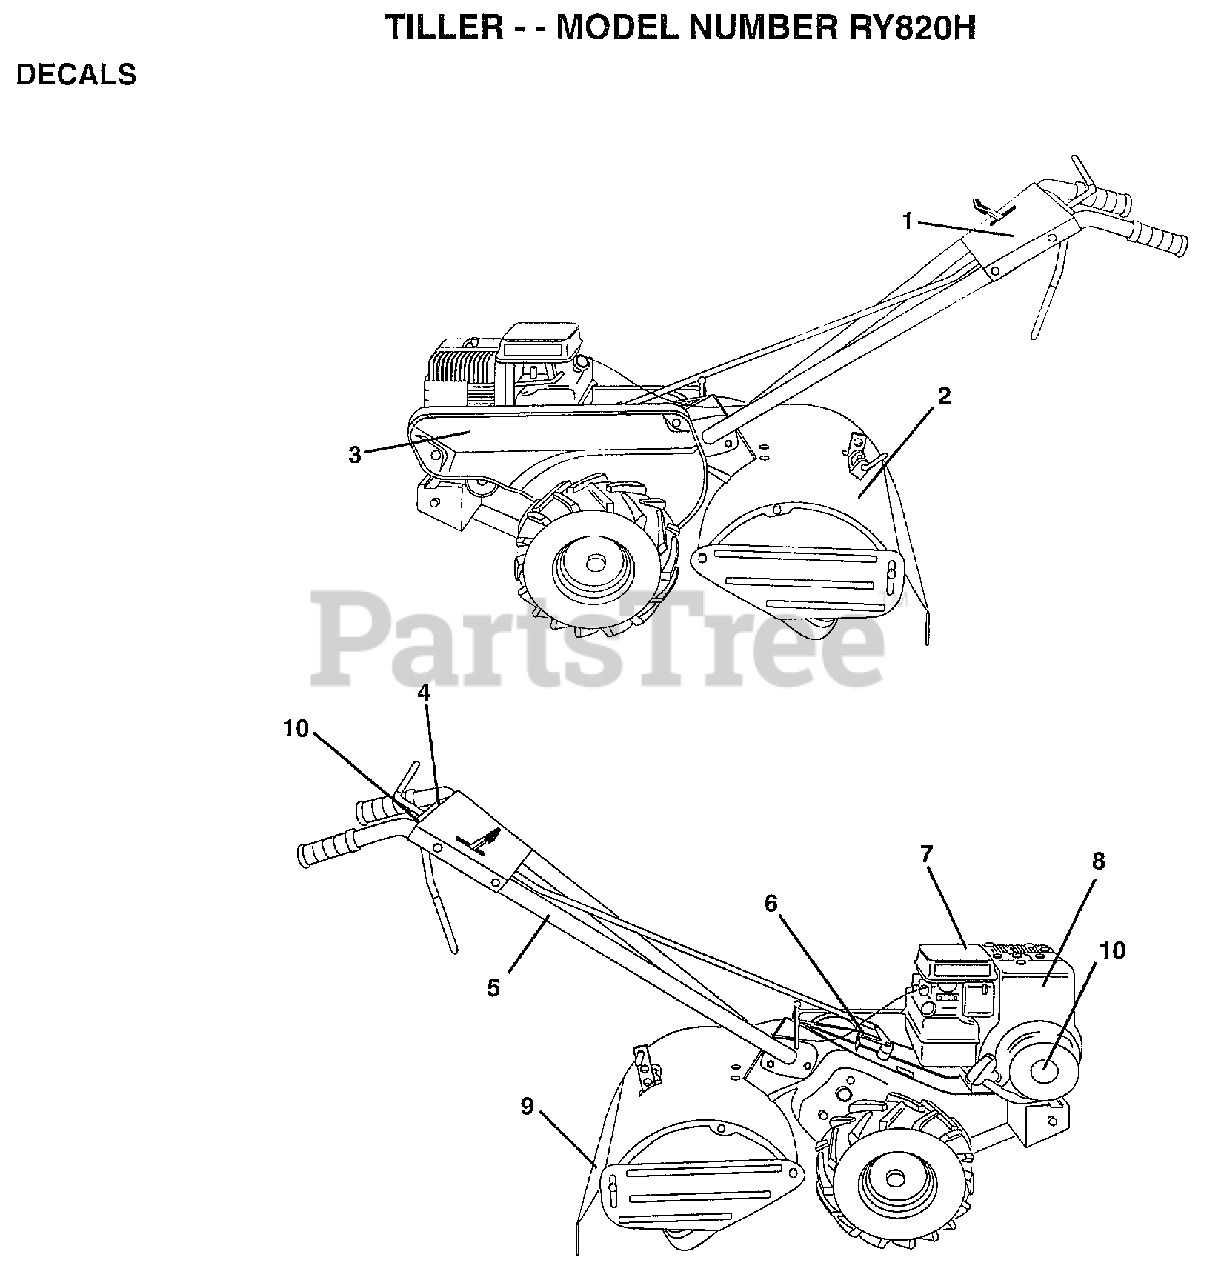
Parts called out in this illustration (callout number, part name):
3	DECAL, LOGO
5	DECAL TI
6	DECAL CRT
7	DECAL TI
8	DECAL, BRIGGS & STRATTON
11	DECAL REVERSE
